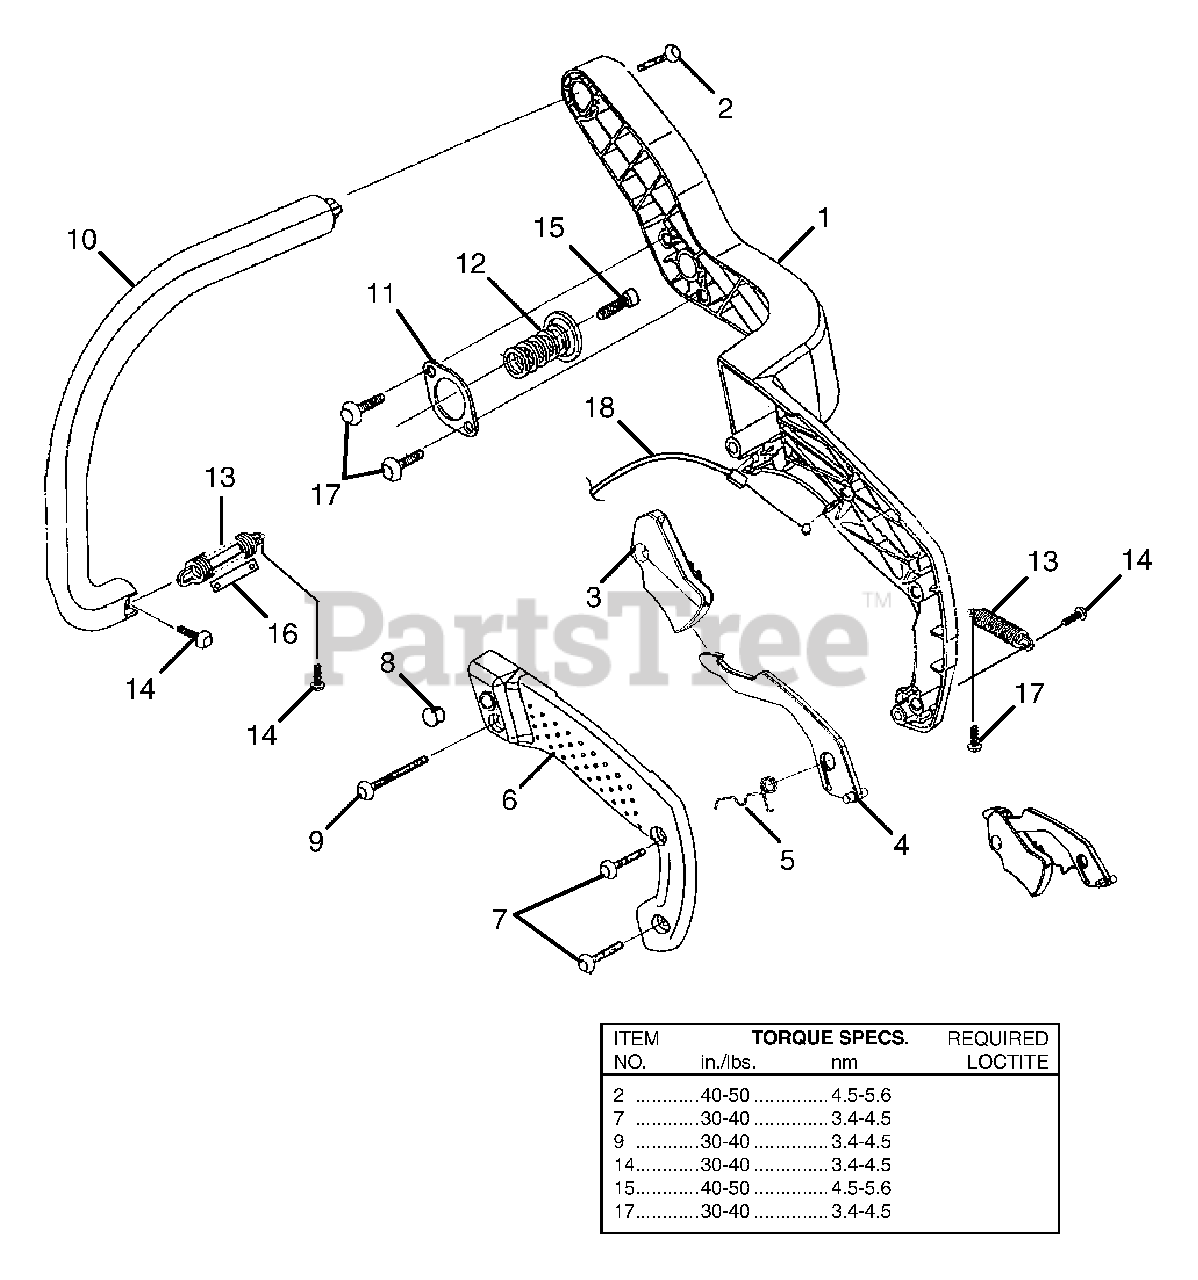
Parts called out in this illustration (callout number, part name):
1	REAR HANDLE
2	SCREW (12-14 x 1-1/2 in.)
3	TRIGGER, THROTTLE
4	THROTTLE LOCK OUT
5	TORSION SPRING
6	HANDLE COVER
7	SCREW (10-14 x 3/4 in.)
8	PLUG-PLASTIC
9	SCREW (10-14 x 1-3/8 in.)
10	FRONT HANDLE KIT
11	ISOLATOR PLATE
12	UPPER ISOLATION SPRING
13	SPRING - ISOLATOR
14	SCREW (10-14 x 5/8 in.)
15	SCREW (10-24 x 5/8 in.)
16	SPRING RETAINER
17	SCREW (10-14 x 1/2 in.)
18	THROTTLE CABLE
